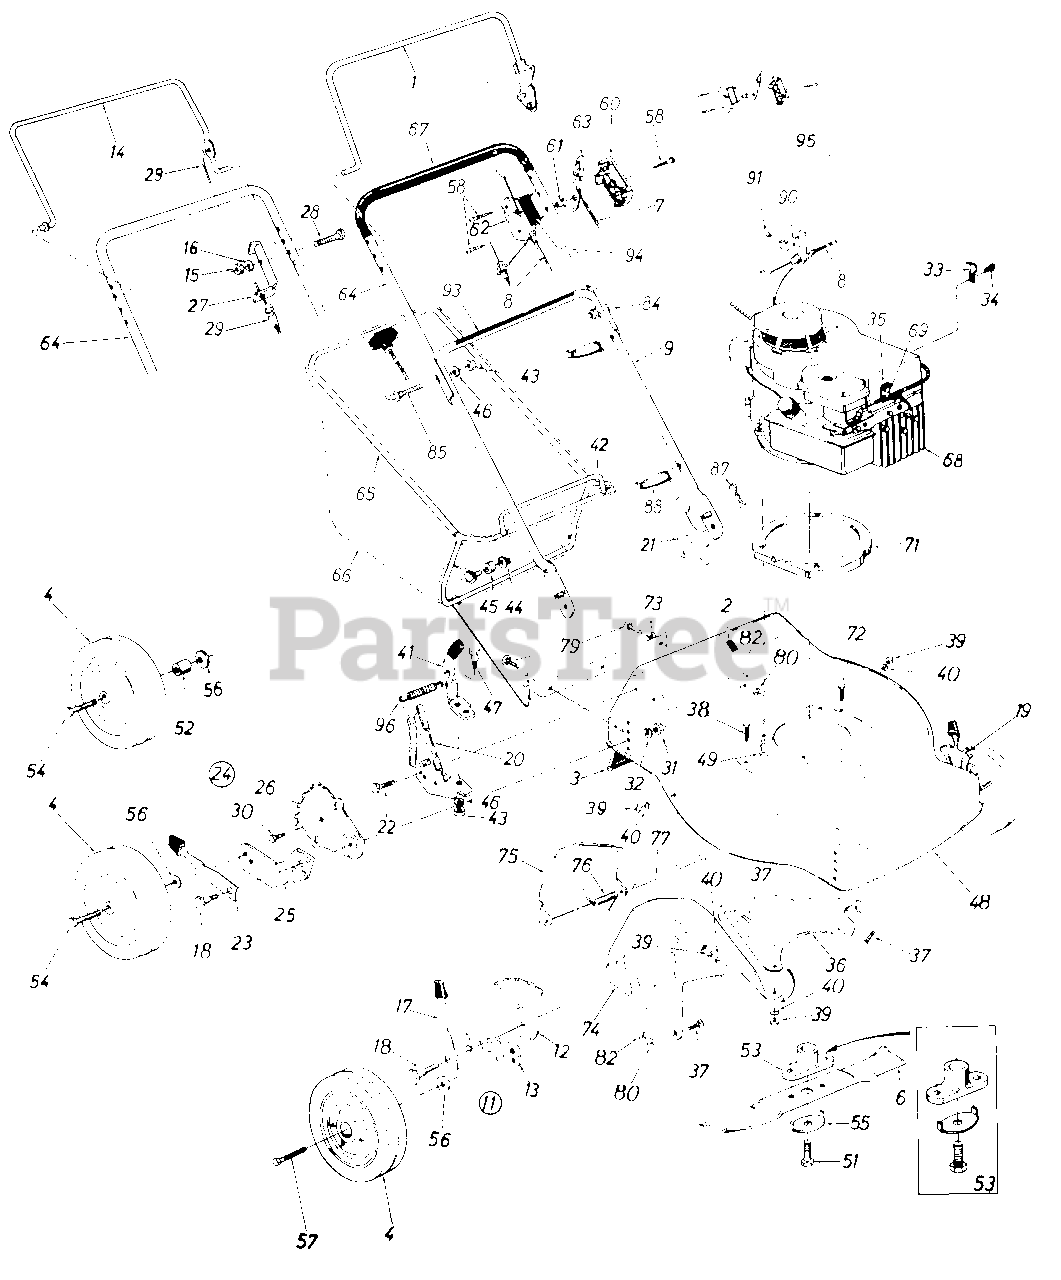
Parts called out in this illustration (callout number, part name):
1	Control Handle Ass'y.
3	Rear Flap Ass'y.
4	7" Wheel Ass'y. Comp.
6	20" Blade
7	Throttle Wire-58"
8	Control Cable-43"
9	Lower Handle
11	Front Height Adj. Ass'y.-R.H.
12	Front Index Plate
13	Front Pivot Bar
14	Control Handle
15	Hex Nut 1/4-28 Thd.
16	Spr. Wash. .265" I.D. x .562"
17	Spring Lever w/Knob
18	Shld. Bolt .50" Dia. x 375
19	Front Height Adj. Ass'y.-L.H.
20	Handle Brkt. Ass'y.-R.H.
21	Handle Brkt. Ass'y.-L.H.
22	Hex Wash. Hd. AB-Tap Scr. 1/4" x .62" Lg.
23	Spring Lever w/Knob
24	Rear Height Adj. Ass'y.-R.H.
25	Rear Pivot Bar-R.H.
26	Rear Index Plate
27	Cable Mounting Bracket
28	Hex Bolt 1/4-28 x 1.75" Lg.
29	Control Cable-55"
30	Hex Wash. Hd. Tap Scr. 1/4 x .62" Lg
31	Hex Nut 3/8-16 Thd.
32	L-Wash. 3/8" I.D.
33	Cable Clip
34	Hex AB-Tap Scr. #10 x .38"
35	Casing Clamp
36	Rear Chute Baffle-L.H.
37	Carr. Bolt 1/4-20 x .50" Lg.
38	Hex Bolt 1/4-20 x .88" Lg.
39	Hex Nut 1/4-20 Thd.
40	L-Wash. 1/4" I.D.
41	Lock Lever w/Knob
44	Push Cap 3/8" Rod
45	Plastic Roller
46	L-Wash. 5/16" I.D.
47	Shld. Bolt .437" Dia. x .162
51	Hex Bolt 3/8-24 x 1.5" Lg. (Grade 5)
52	Spacer
53	Blade Adapter Kit
54	Rear Axle Bolt
55	Blade Bell-Wash.
56	Bell-Wash. .400" I.D. x .88"
57	Front Axle Bolt
58	Truss Mach. Hi-B Tap Scr. #12 x 1.5" Lg.
60	Control Panel Half
61	Control Disc Pin
62	Clutch Panel Half
63	Throttle Control Lever
64	Upper Handle
65	Grass Catcher Upper Frame
66	Grass Bag
68	Engine
69	Hex AB-Tap Scr. #8 x .38n
71	Engine Mounting Cover
72	Hex Self-Tap Scr. 1/4-20 x .75"
73	Grass Catcher Hitch Brkt.
74	Rear Chute Baffle-R.H.
75	Chute Door
76	Torsion Spring
77	Hinge Pin
79	Carr. Bolt 1/4-20 x .75" Lg.
80	Hex Sems Nut 1/4-20 Thd.
82	Fl-Wash. .281" I.D. x 1.25"
84	Curved Carr. Bolt 5/16-18 x 1.38" Lg.
85	Rope Guide Bolt
87	Hairpin Cotter
88	Cable Tie
90	Cable Brkt.
91	Pop Rivet
93	Instruction Label-Handle
94	Control Label-Throttlet
95	Kit-Control Housing Comp.
96	Tension Spring
